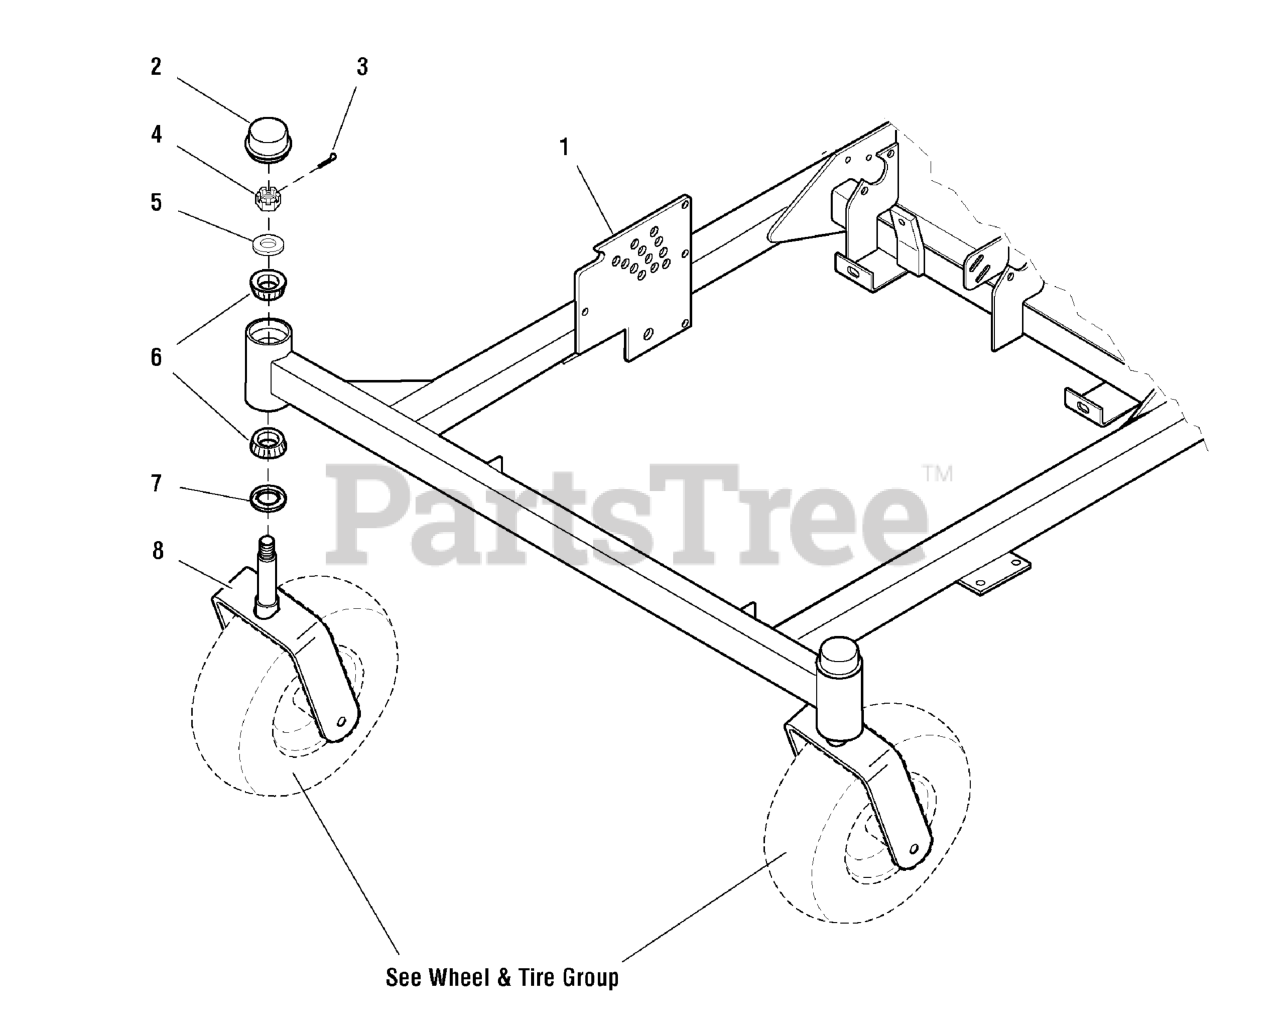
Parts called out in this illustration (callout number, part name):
1	61" MAIN FRAME
2	CAP
3	PIN, COTTER, 1/8 X 1-1/4
4	NUT, 3/4-16 Hex Slotted
5	WASHER, 3/4 SAE
6	BEARING, Tapered Roller
7	SEAL, GREASE
8	CASTER TIRE MOUNT
